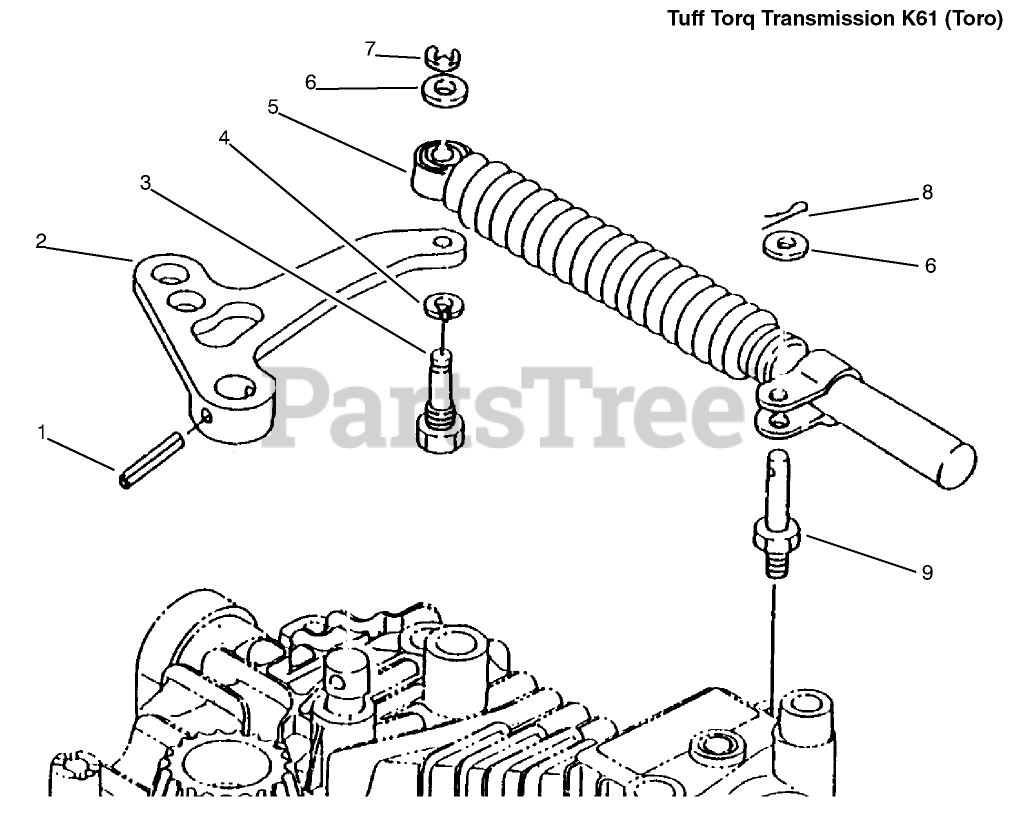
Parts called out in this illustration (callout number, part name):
1	PIN-ROLL
4	WASHER
6	WASHER
8	PIN-COTTER
